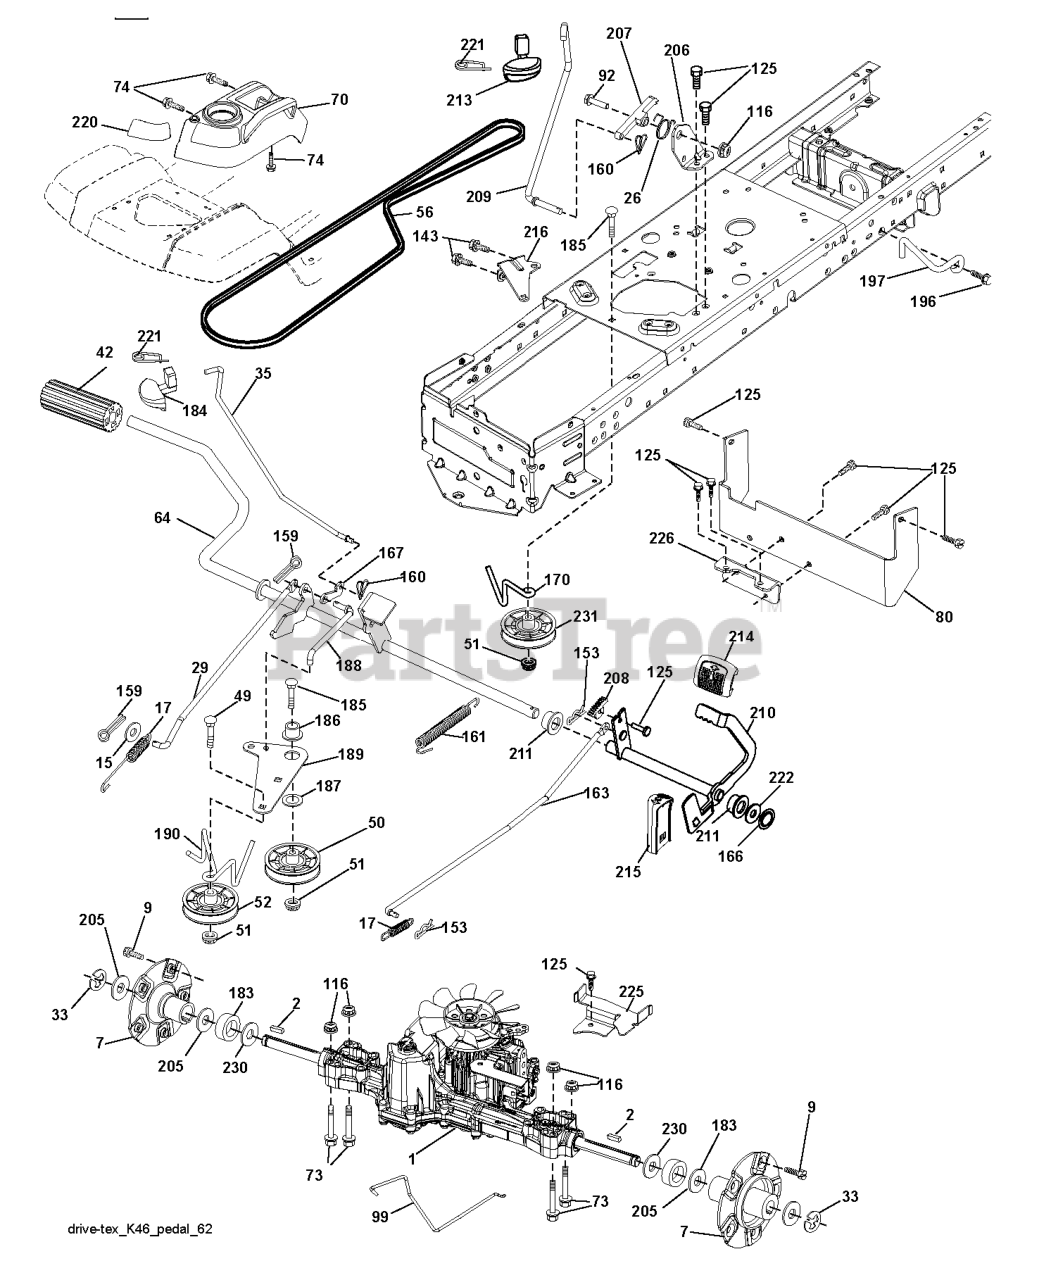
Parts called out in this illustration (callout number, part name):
2	KEY.SQUARE.187X2.500
7	HUB.ASM.WHEEL.REAR.22"
15	WASHER
17	SPRING.BRAKE.K46.GREEN
26	SPRING.RETURN.CRUISE
29	ROD.BRAKE.K46
35	ROD.BRAKE.PARKING.GT.H
42	PEDAL COVER T
50	IDLER.FLAT.910.OFFSET
51	NUT LOCK FLG 3/8-16 UNC
52	IDLER.V-GROOVE.910.OFFSET
56	V-BELT.MOWER.92.40.42/K46
64	SHAFT.ASM.PEDAL.BRK.CNTR
70	RP CONSOLE.ASM.PCH.W/TB
73	BOLT HEX 5/16-18 GR 5
74	SCREW.HI-LO.CONSOLE
80	STRAP TORQUE
92	BOLT
99	ROD.SPRING.BYPASS.K46.LT.Z
116	NUT LOCK HEX FLANGE 5/16-18
125	SCREW
143	Screw 5/16-18 x 1/2 Hex, Self Tapping 5/16-18 x 1/2
153	RETAINER M
159	COTTER PIN
160	RETAINER CLIP
161	SPRING, RETURN LT
163	ROD.CONTROL.PEDAL.K46
166	NUT.PUSH.625
167	LATCH.BRAKE.SPRING
170	KEEPER.CENTER SPAN.1.688
183	SPACER.SPLIT.800X.350
184	HANDLE.PARKG.BRK.HUSQ X667
186	SPACER.RETAINER
187	WASHER 12/32X2X10GA
188	RP.LINK.CLUTCH.GROUND.DRIVE
189	BELLCRANK.GROUND.DRIVE.TEX.
190	KEEPER.BELLCRANK.DRIVE
196	SCREW 3/8-16X1
197	BRKT.ANIT-ROTATION.CLUTCH
206	BRKT.MOUNT.LATCH.CRUIS
207	LATCH.CONTROL.CRUISE
208	GEAR.SECTOR.CONTROL.CR
209	ROD.CONTROL.CRUISE.GT.
210	ROCKER.ASM.PEDAL.CONTR
211	BEARING.NYLON
213	KNOB.CONTROL.CRUSIE.HU
214	PEDAL.FORWARD.PAD.TEX
215	PEDAL.REVERSE.TEX.GT.4
216	BRACKET.PULLEY.IDLER.W/TEX
220	REFLECTOR.RH.TEX GT
221	RETAINER.SPRING.CLIP.H
222	WASHER 21/32 X 1-1/4 X 10 GA.
225	KEEPER.BELT.TRANSAXLE.K46
226	BRACKET.MOUNT.TORQUE.K46.TLT
230	WASHER.HARDENED
231	IDLER.V-GROOVE.1.688.OFFSET
